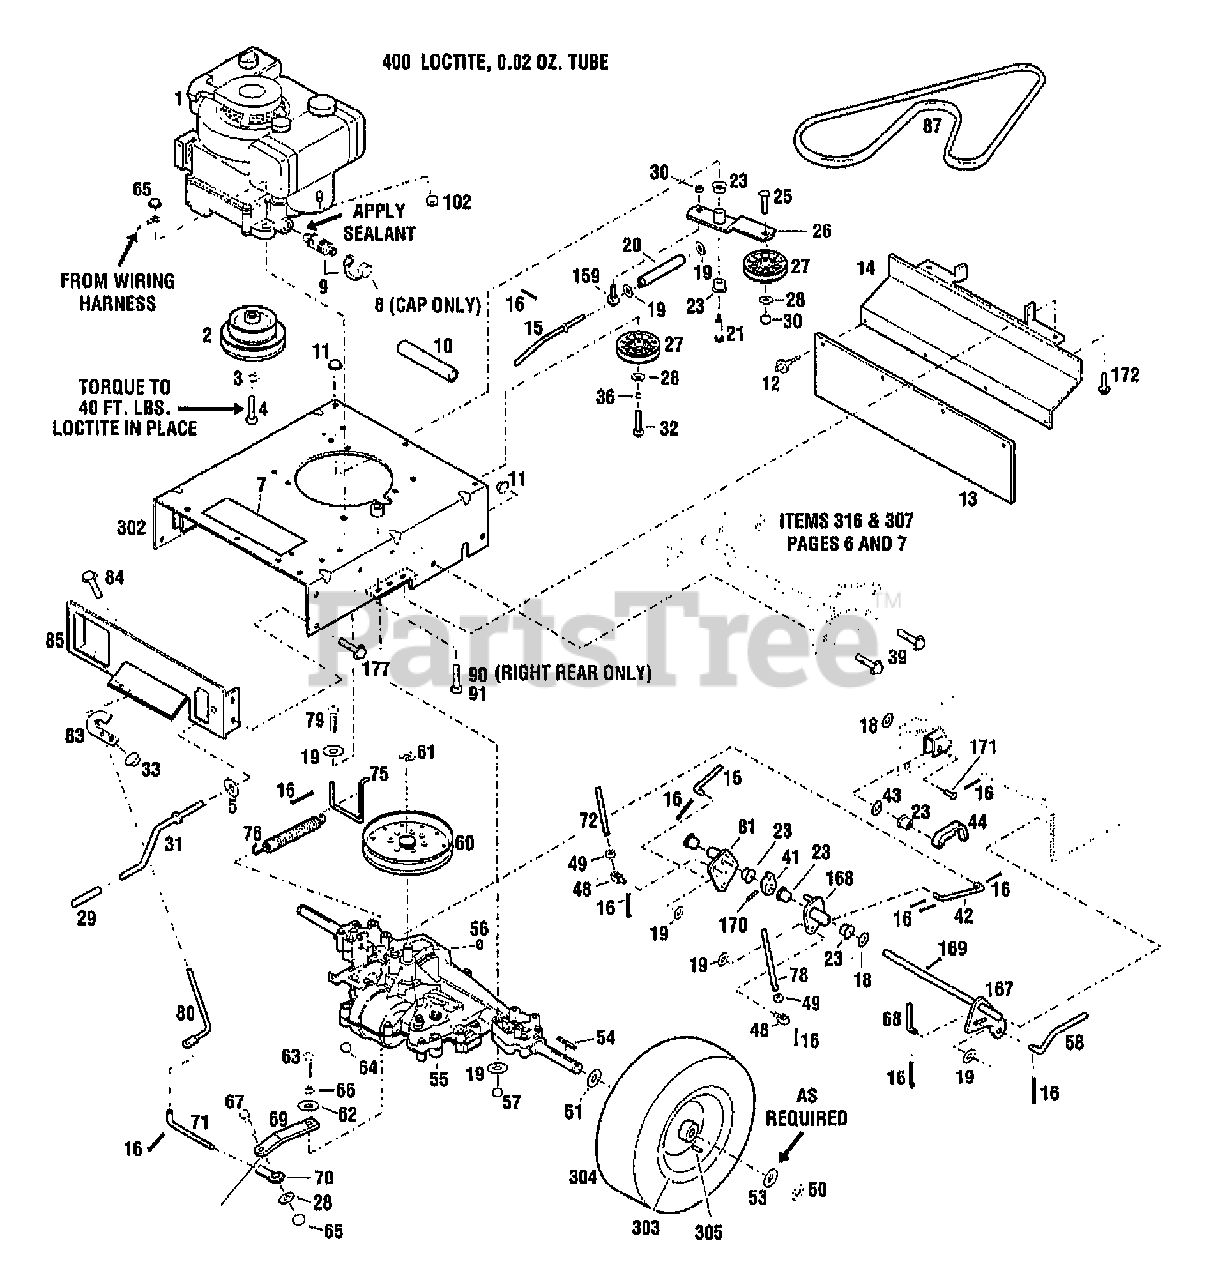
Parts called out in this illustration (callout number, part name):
1	ENGINE 8.5HP, ELECTRIC START
1	ENGINE 8.5HP, RECOIL START
2	PULLEY-ENGINE
3	WASHER-LK .438 ZP
4	SCR-HHC 7/16-20X1.75
5	WASHER-NYLON
7	DECAL-WARNING
8	CAP-OIL DRAIN
9	ASSM-OIL VALVE
10	HOSE-OIL DRAIN
11	NUT-HFLK 3/8-16 ZP
12	RIVET-POP 3/16 X 5/8
13	FLAP-SAFETY
14	FLAP BRACKET
15	ROD-LOWER TRANS
16	PIN-COTTER .093X.625
18	WASHER-FLAT .88X.5X.06 ZP
19	WASHER-FLAT 5/16 SAE
20	SPRING-COMPRESSION
21	SCR-SHLDR 3/8-16
23	BUSHING-.5X.5 NYLON FLNG
25	SCR-CARR 3/8-16X1.75 G5 ZP
26	ASSM-IDLER ARM ZP
28	WASHER-FLAT 3/8 SAE
29	GRIP-PLASTIC
30	NUT-LOCK 3/8-16
31	ASSM-CRANK LIFT {34089,34089C,34087,34087C}
31	CRANK-DECK LIFT {34342,34343}
32	SCR-HH 3/8-16X1.75 G5 ZP
33	NUT-HF/LK 1/4-20 ZP
36	WASHER-LK .375 @ DEPL
39	SCR-HFLK 3/8-16X1.00 ZP
41	CAM-INTERLOCK
42	ROD-LOWER BRAKE
43	WASHER-FLAT 1.0X.516X.031
44	LATCH-INTERLOCK
48	BLOCK-SWIVEL ZP
49	NUT-HEX JAM 5/16-18
50	RING-RET."E".577 ID
51	WASHER-1.5X.755X.062
53	WASHER-1.25X.765X.049
54	KEY-.188 SQ X 2.25
55	TRANSMISSION ASSEMBLY, MODEL 915-027 (SEE PAGE 10 FOR BREAKDOWN)
56	KEY-WOODRUFF .188X.75
57	NUT-TOP/LK 5/16-18 ZP
58	ROD-LOWER BLADE
60	PULLEY-TRANSAXLE
61	RING-RETAIN .625 ID
62	WASHER-FLAT 1/4 SAE
63	SCR-HH 1/4-28X.75 G5 ZP
64	NUT-HFLK 5/16-18 ZP
65	NUT-H/LK 3/8-16
66	WASHER-LK .25 ZP
67	SCR-HH 3/8-16X1.25
68	ROD-UPPER BLADE
69	ARM-TRANSMISSION ZP
70	JOINT-BALL
71	ROD-SHIFT LINK
72	ROD-UPR TRANSMISSION
75	ROD-SPRING ATTACHMENT
76	SPRING-EXTENSION
78	ROD-UPPER BRAKE
79	SCR-HH 5/16-18X2.75 G5 ZP
80	LEVER-SHIFT
81	ASSM-CLUTCH ARM ZP
83	BRKT-SHIFT ROD MTG
84	SCR-HFLK 1/4-20X.50 ZP
85	PLATE-BACK
90	SCR-THRD FRM 3/8-16X1.50
91	SCR-HH 3/8-16X1.0 THDFM
102	NUT-HEX 1/4-20 ZP
159	BOLT-EYE
167	SHAFT-PIVOT ZP
168	ASSM-BRAKE ARM ZP
169	PIN-COTTER .120X1.00 ZP
170	PIN-ROLL .156X1.0
171	PIN-CLEVIS .5X1.25
172	SCR-HFLK 5/16-18X.75
177	SCR-HFLK 5/16-18X.625 STH
302	ASSM-FRAME {34089,34089C,34087,34087C} ( INCL. 7)
302	FRAME W/DECAL {34342,34343} (INCL. 7)
304	TIRE
305	STEM-VALVE
400	LOCTITE-242 (.5 ML TUBE)
